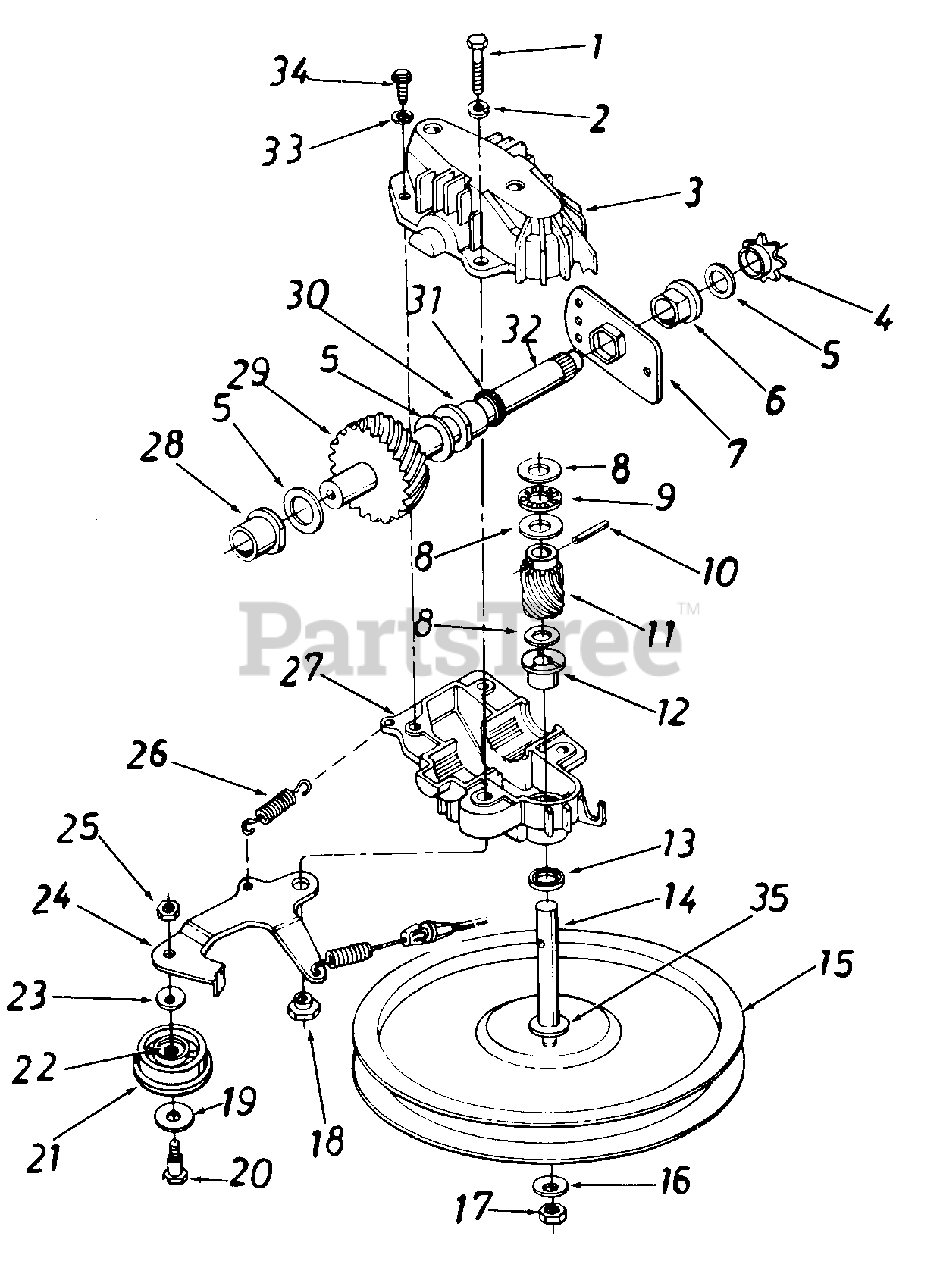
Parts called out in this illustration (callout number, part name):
1	Hex Bolt 1/4-20 x 1.25" Lg.
2	L-Wash. 1/4" I.D.
3	Upper Transmission Hsg. Half
4	#48 Sprocket 7 Tooth x 1/2 Pitch
5	Fl-Wash. 5/8" l.D. x .030
6	Hex Flange Brg. .631" I.D.
7	Hex Bearing Cup
8	Thrust Wash. .382" I.D. x .70" O.D.
9	Thrust Bearing .375" I.D. x .812" O.D.
10	Spring Pin Spir. 1/8" x .62" Heavy
11	11 Tooth Helical Gear
12	Flange Bearing
14	Pulley-Transmission Shaft .375 O.D.
15	Fl-Pulley 5.06" O.D.
16	Bell-Wash. .265" I.D. x .75"
17	Hex Lock Nut 1/4-28 LH Thd.
18	Shld. Spacer .375' Dia. x .170
19	Fl-Wash. .390" I.D. x 1.0"
20	Shld. Bolt .375" Dia. x .40"
21	Fl-ldler Plastic 1.50" Dia. x .48
22	Needle Brg 375' x 31
23	Bell-Wash. .265" I.D. x 75"
24	Idler Brk't. Ass'y.
25	Hex Patch L-Nut 1/4-28 Thd.
26	Extension Spring 1.12" Lg.
27	Lower Transmission Hsg. Half
28	Flange Bearing .566 Dia.
29	33 Tooth Helical Gear
30	Flange Bearing .629 Dia.
31	Oil Seal .625 Dia.
32	Gear Sprocket Shaft
34	Hex B-Tap Scr. #10 x .62"
35	Hex Washer .26" x .88"
